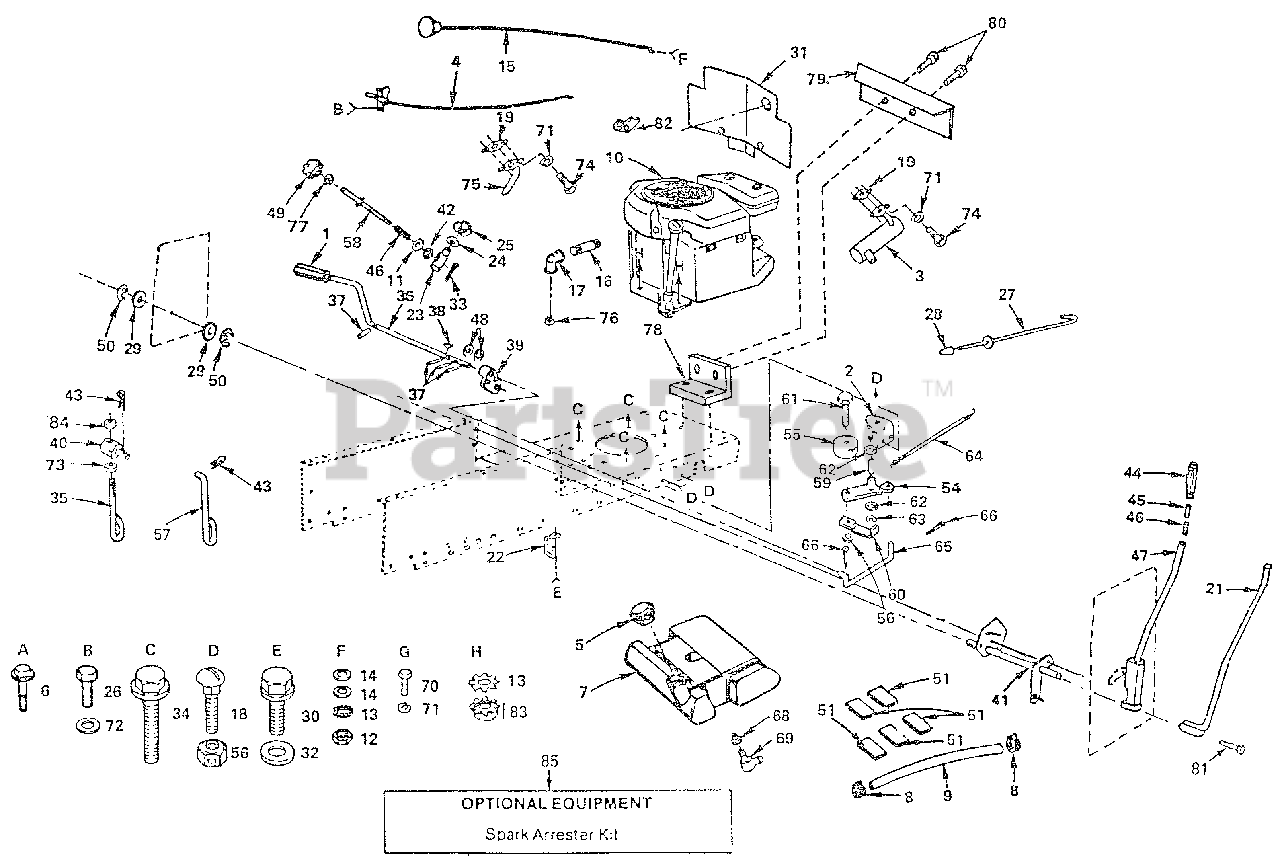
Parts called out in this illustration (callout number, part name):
1	Pedal Cover
2	Bracket Assembly - Clutch
4	Control, Throttle/Choke
5	Fuel-Cap Assembly
6	Screw - Hex Hd. Thd. Cutting 8-32 x 3/8, Type T
8	Hose Clamp
9	Fuel Line
10	Engine 14 HP, Type No. 1211-01
11	Washer 13/32 x 5/8 x 16 Ga.
16	Std. Pipe Nipple
17	90 Elbow 3/8 NPT
18	Bolt Rd. Hd Sq. Neck 3/8 16 x 3/4
19	Gasket, Muffler
21	Rod Assembly - Lever
22	Retainer. Belt, Chassis, L.H.
23	Trunnion - Stop, Depth
24	Washer 15/32 x 3/4 x 16 Ga.
26	Screw- Hex Washer Hd Thd. Cutting 1/4-20 x 1/2
27	Rod- Brake, Park
28	Plunger Cap
29	Washer 29/32 x 1 - 1/4 x 16 Ga
30	Screw - Hex Washer Thd Rolling 3/8- 1 6 x 3/4
31	Baffle Vertical
32	Washer 13/32 x 13/16 x 12 Ga.
33	Cotter Pin 3/32 x 1/2
34	Screw - Hex Washer Hd. Thd. Rolling 3/8-16 x 1 1/4 Type TT
35	Lift Link - Adjustable
36	Shaft Pedal Foot
37	Roll Pin 3/16 x 1
39	Bearing, Nylon
40	Trunnion, Lift
41	Shaft Assembly- Lift
42	Nut - Hex Special
43	Retainer Spring
44	Grip- Handle
45	Plunger- Lever, Hand
45	Button - Plunger
46	Spring
47	Lever Assembly, Hand Kit
48	Washer 21/32 x 1 x 16 Ga.
49	Handle - Adjust, Lift
51	Pad-Spacer
54	Bellcrank Assembly
55	Pulley - Idler
56	Locknut 3/8 - 16
57	Link - Lift
58	Rod-Adjust, Lift
60	Retainer Belt
61	Bolt - Hex 3/8 - 16 x 1-1/2
62	Washer- Hardened
63	Ring- Klip
64	Spring- Return, Clutch
65	Link- Clutch
66	Pin- Cotter 1/8 x 3/4
69	Stem-Tank, Fuel
70	Bolt - Hex 1/4 - 20 x 1/2
71	Lockwasher 1/4
73	Nut Hex Jam 7/16 - 20
74	Bolt - Hex 1/4 - 20 x 1/4
75	Tube Assembly - Exhaust
76	Plug - Oil Drain
77	Nut - Hex Jam 3/8 - 16
78	Bracket - Heat Shield
79	Heat Shield
80	Bolt - Hex Thread Cutting 5/16 - 18 x 1/2
81	Bolt,Hex Hd. 3/8 - 16 x 1-1/2
82	Clip, Insulated
83	Nut,Keps 3/8 - 16
84	Nut,Crownlock 7/16-20
85	Spark Arrestor Kit
